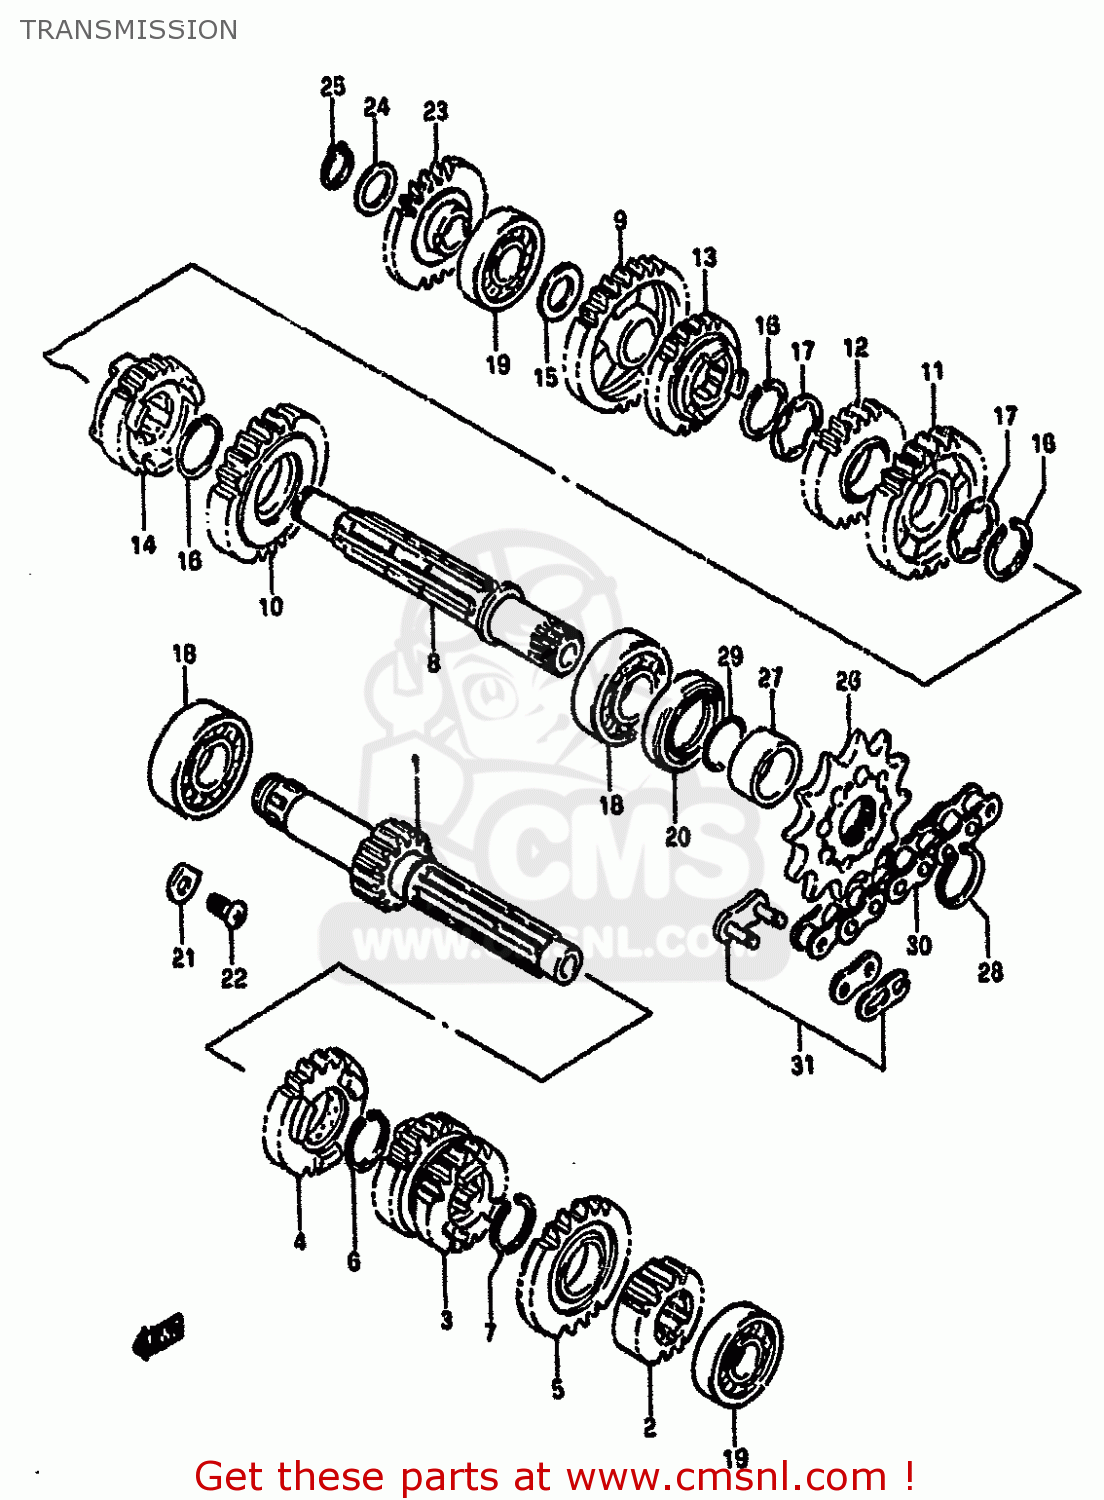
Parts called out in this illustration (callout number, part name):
1	SHAFT,COUNTER
2	GEAR,SECOND DRIVE (NT:16)
3	GEAR,THIRD & FOURTH DRIVE,N
4	GEAR,FIFTH DRIVE (NT:19)
5	GEAR,SIXTH DRIVE (NT:20)
6	CIRCLIP
7	CIRCLIP
8	SHAFT,DRIVE
9	GEAR,1ST DRIVEN
10	GEAR,SECOND DRIVEN (NT:28)
11	GEAR,THIRD DRIVEN (NT:23)
12	GEAR,FOURTH DRIVEN (NT:24)
13	GEAR,FIFTH DRIVEN (NT:20)
14	GEAR,SIXTH DRIVEN (NT:19)
15	WASHER,THRUST
16	CIRCLIP
17	WASHER,LOCK
18	BEARING
19	BEARING
20	SEAL,OIL(25X40X7)
21	RETAINER,SHIFT CAM,R BEARING
22	SCREW 6X12
23	GEAR,KICK STARTER IDLE
24	WASHER,THRUST
25	CIRCLIP,15MM
26	SPROCKET,ENGINE
27	SPACER (20X25X12.8)
28	CIRCLIP
29	O RING(D:1,ID:19.5)
30	CHAIN ASSEMBLY,DRIVE
31	JOINT ASSEMBLY,CHAIN
